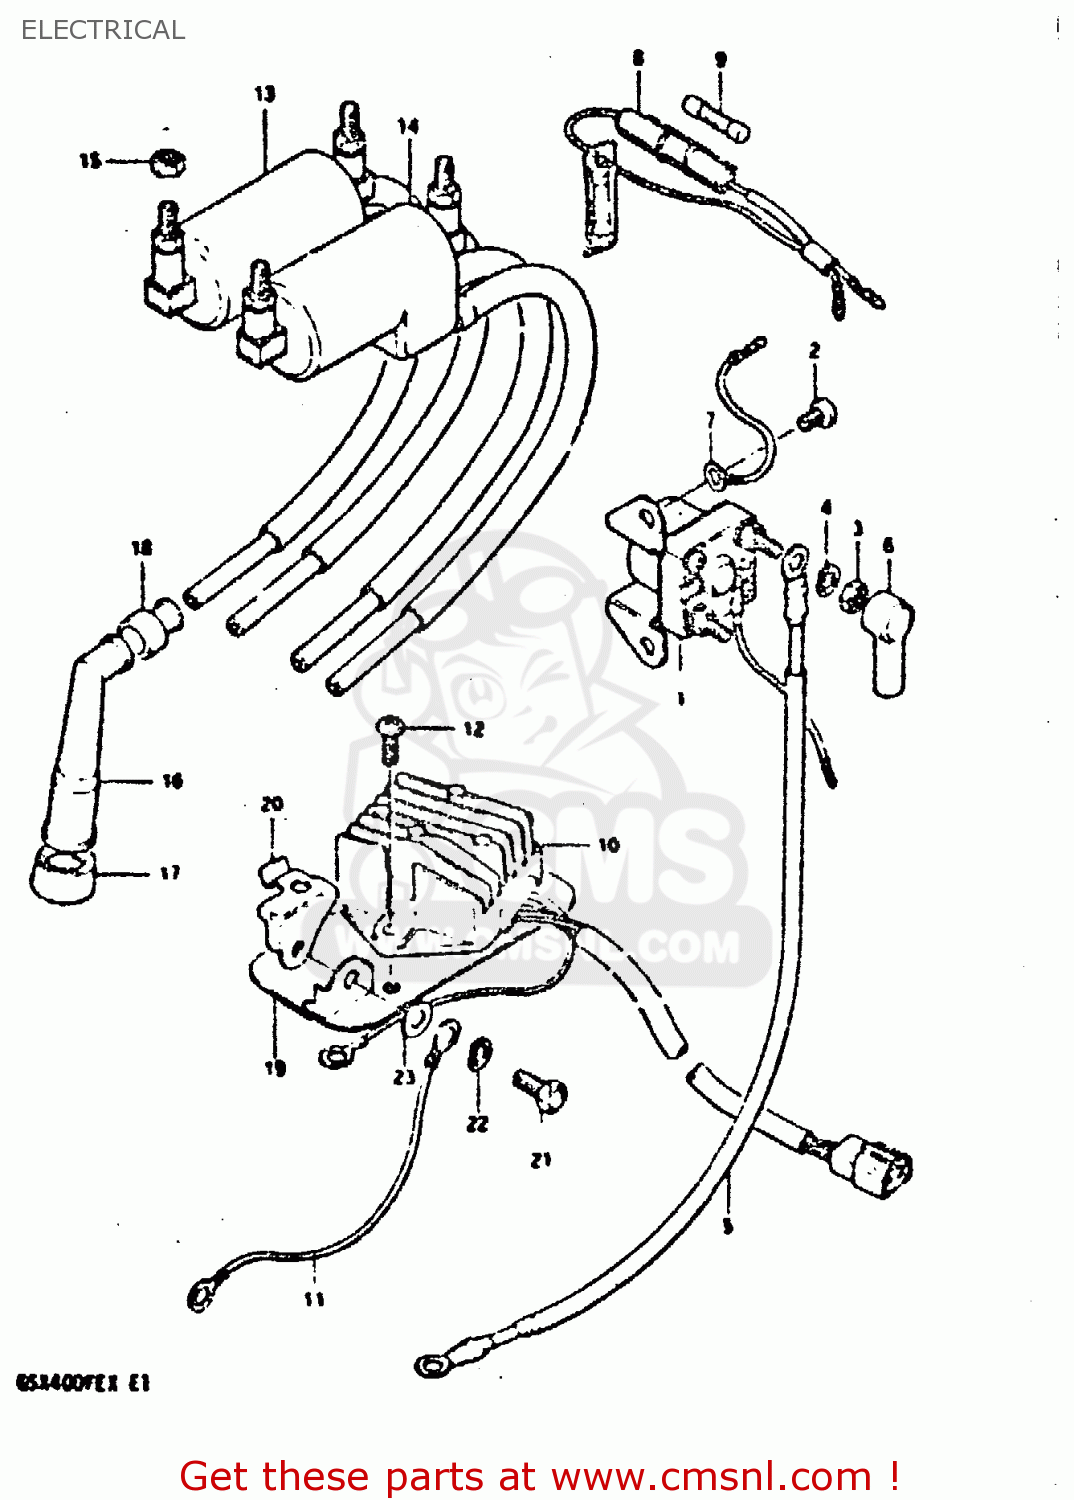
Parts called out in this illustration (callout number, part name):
1	RELAY, STARTING MOTOR
2	SCREW,6X6
3	NUT 6MM
4	LOCK WASHER
5	WIRE,STARTER MOTOR LEAD
6	CAP,STARTER RELAY
7	LEAD WIRE
8	BOX ASSEMBLY,FUSE
9	FUSE(15A)
10	RECTIFIER, REGULATOR
11	LEAD WIRE,EARTH
12	SCREW
13	COIL, IGNITION NO. 1
14	COIL, IGNITION NO. 2
15	NUT
16	CAP ASSY,SPARK PLUG
17	SEAL,SPARK PLUG
18	SEAL,SPARK PLU
19	PLATE, PARTS HOLDER
20	BRACKET
21	BOLT
22	LOCK WASHER
23	WASHER
